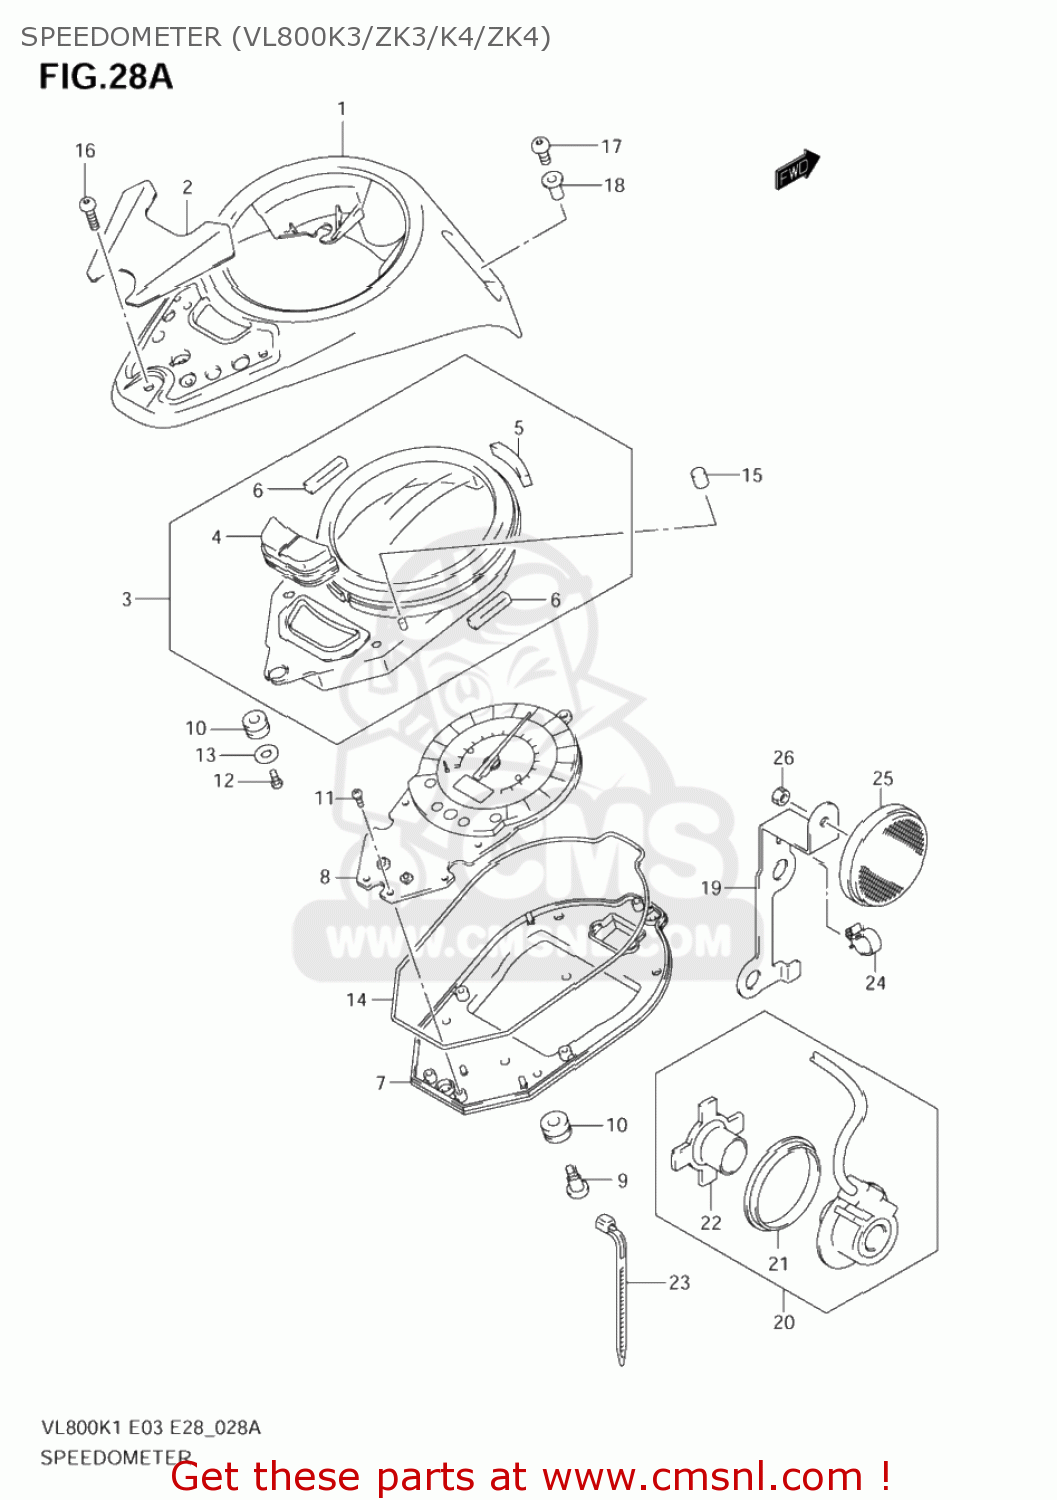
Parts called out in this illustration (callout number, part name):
1	CASE ASSY
2	PLATE,DECORATION
3	CASE,UPR
4	SWITCH,SELECT
5	CUSHION NO.1
6	CUSHION NO.2
7	CASE,LWR
8	SPEEDOMETER
9	BOLT
10	CUSHION,METER
11	SCREW(3X10)
12	SCREW(4X14)
13	WASHER
14	GASKET,METER CASE (NAS)
15	CUSHION NO.4
16	SCREW(5X14)
17	SCREW(5X18)
18	NUT
19	GUIDE,SENSOR LEAD LWR
20	SENSOR,SPEED
21	SEAL,OIL(44X55X6)
22	ROTOR,SPEEDOMETER
23	CLAMP(L:145)
24	CLAMP
25	REFLECTOR,REFLEX FR
26	NUT
